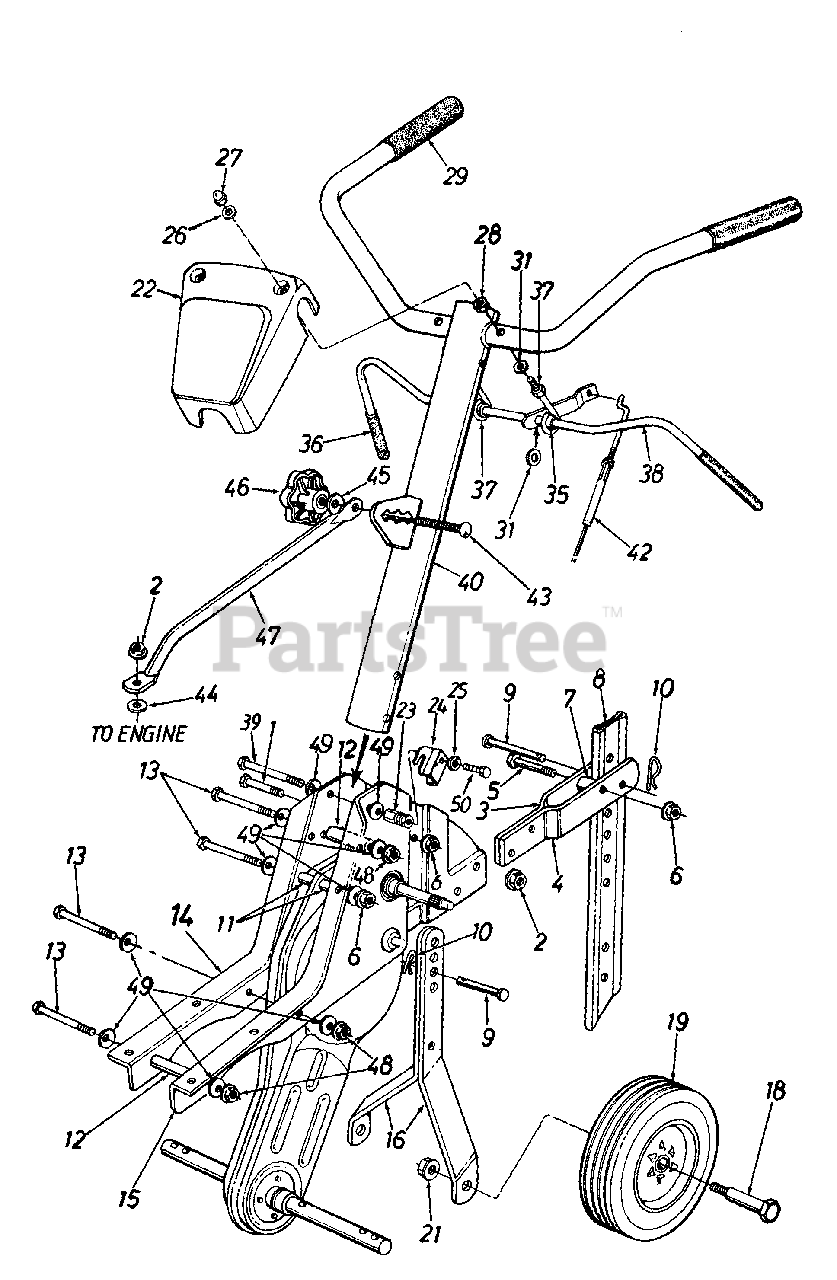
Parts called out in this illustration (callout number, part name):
1	Hex Bolt 5/16-18 x 1.25" Lg.
2	Hex Flange L-Nut 5/16-18 Thd. (Gr. 5)
5	Hex Bolt 5/16-18 x 1.5" Lg.
6	Hex Flange L-Nut 5/16-18 Thd.
7	Spacer .32" I.D. x .75" O.D.
9	Clevis Pin .375" I.D. x 1.75" Lg.
10	Internal Cotter Pin
11	Spacer .326" I.D. x .47" O.D.
12	Spacer .322" I.D. x .44" O.D.
13	Hex Bolt 5/16-18 x 2.75" Lg.
19	Wheel Ass'y.
21	Hex Flange L-Nut 3/8-16 Thd. (Gr. 5)
25	L-Wash. 5/16" I.D.
26	Fl - Wash. .266" I.D. x .625" O.D.
27	Hex L-Stop Nut 1/4-28 Thd.
28	Hex Nut 1/4-28 Thd.
29	Grip - Handle
31	Fl - Wash. .385" I.D. x .62" O.D.
35	Plastic Bushing .38" I.D.
36	Grip - Clutch
37	Clutch Handle Eye Bolt
43	Carr. Bolt 5/16-18 x 1" Lg. (Special)
44	Fl - Wash. .344" I.D. x 1.12" O.D.
45	Bell - Wash. .345" I.D. x .88" O.D.
49	Bell - Wash. .345" I.D. x .88" O.D.
50	Hex Bolt 5/16-18 x .75" Lg. (Gr. 5)
